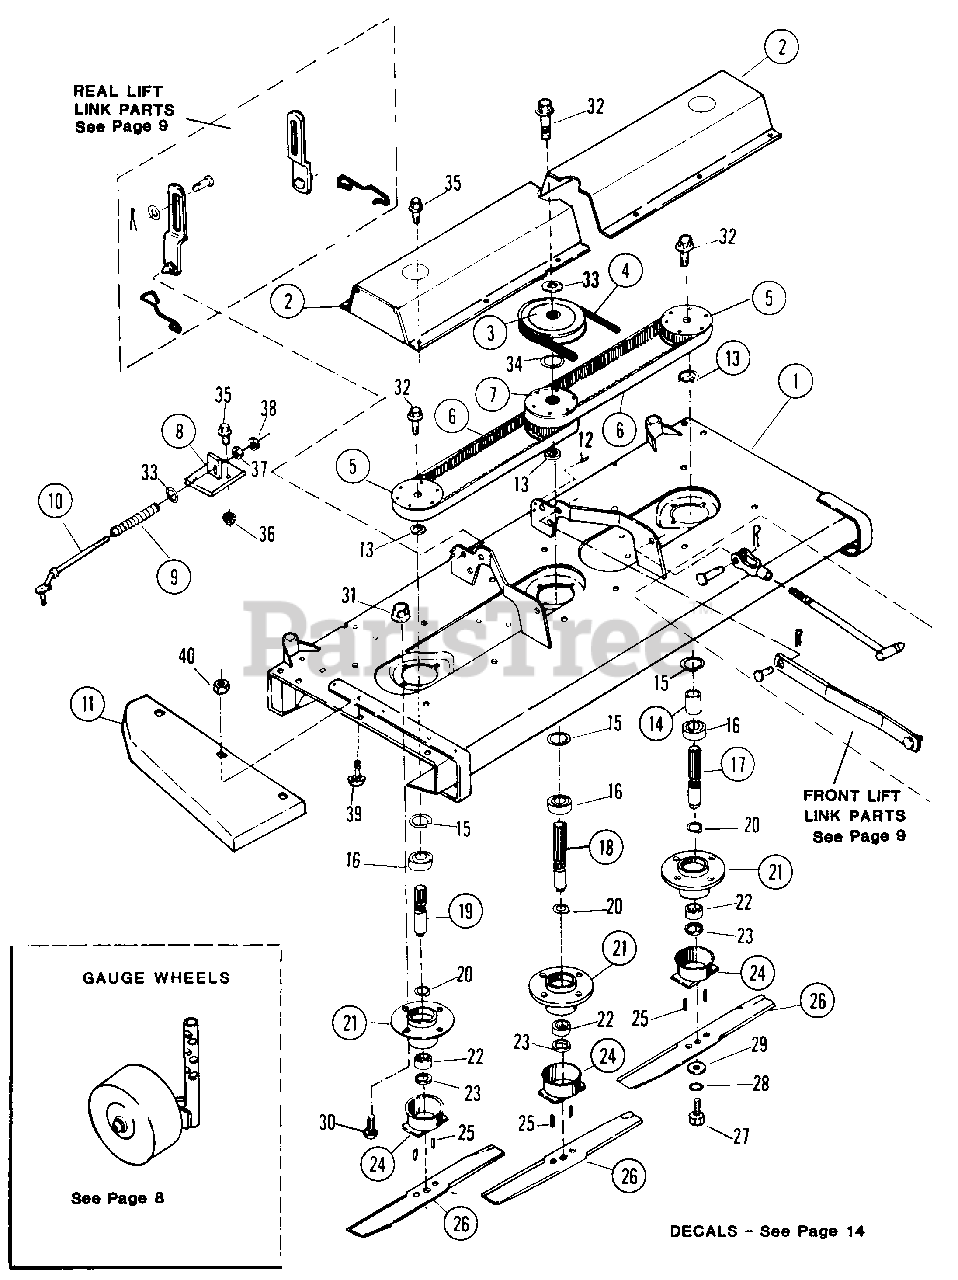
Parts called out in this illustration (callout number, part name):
1	(NLA) MOWER HOUSING WELDMENT 48"
2	(NLA) COVER, TIMING BELT
3	PULLEY, MOWER DRIVE
4	BELT, MULE DRIVE
5	PULLEY, TIMING BELT - RIGHT & LEFT SIDE
6	BELT, DECK BLADE TIMING
7	PULLEY, CENTER TIMING BELT
8	BRACKET, BELT ADJUSTING
9	SPRING, BELT ADJUSTER
10	ROD, BELT ADJUSTING
11	CHUTE, MOWER SIDE DISCHARGE
12	PIN, SPIROL
13	SPACER, PULLEY
14	SPACER, LEFT SIDE PULLEY
15	RING, RETAINING
16	BEARING, BALL, .98" ID, 2.04" OD, .59" Wide
17	SHAFT, LEFT SIDE SPINDLE
18	SHAFT, CENTER SPINDLE
19	SHAFT, RIGHT SIDE SPINDLE
20	RING, RETAINING
21	HOUSING, SPINDLE
22	(NLA) BEARING, NEEDLE
23	SEAL, OIL
24	MOUNTING, CUTTING BLADE
25	PIN, BLADE MOUNTING SHEAR
26	BLADE, MOWER CUTTING
27	BOLT, 1/2 x 1-1/4 HEX HEAD
28	WASHER, 1/2 SPLIT LOCK
29	WASHER, BLADE TO SPINDLE CONE
30	BOLT, 3/8C x 1-1/8 CARRIAGE
31	NUT, 3/8C HEX FLANGE LOCK
32	BOLT, 3/8C x 1 HEX FLANGE LOCK
33	WASHER, 3/8" Flat
34	SHIM, .030"
34	SHIM, .060"
35	NUT, 5/16C HEX FLANGE LOCK
36	NUT, 5/16C HEX FLANGE LOCK
37	NUT, 3/8C HEX
38	NUT, 3/8C HALF HEX
39	BOLT, 1/4C x 3/8 CARRIAGE
40	NUT, 1/4C HEX FLANGE LOCK
